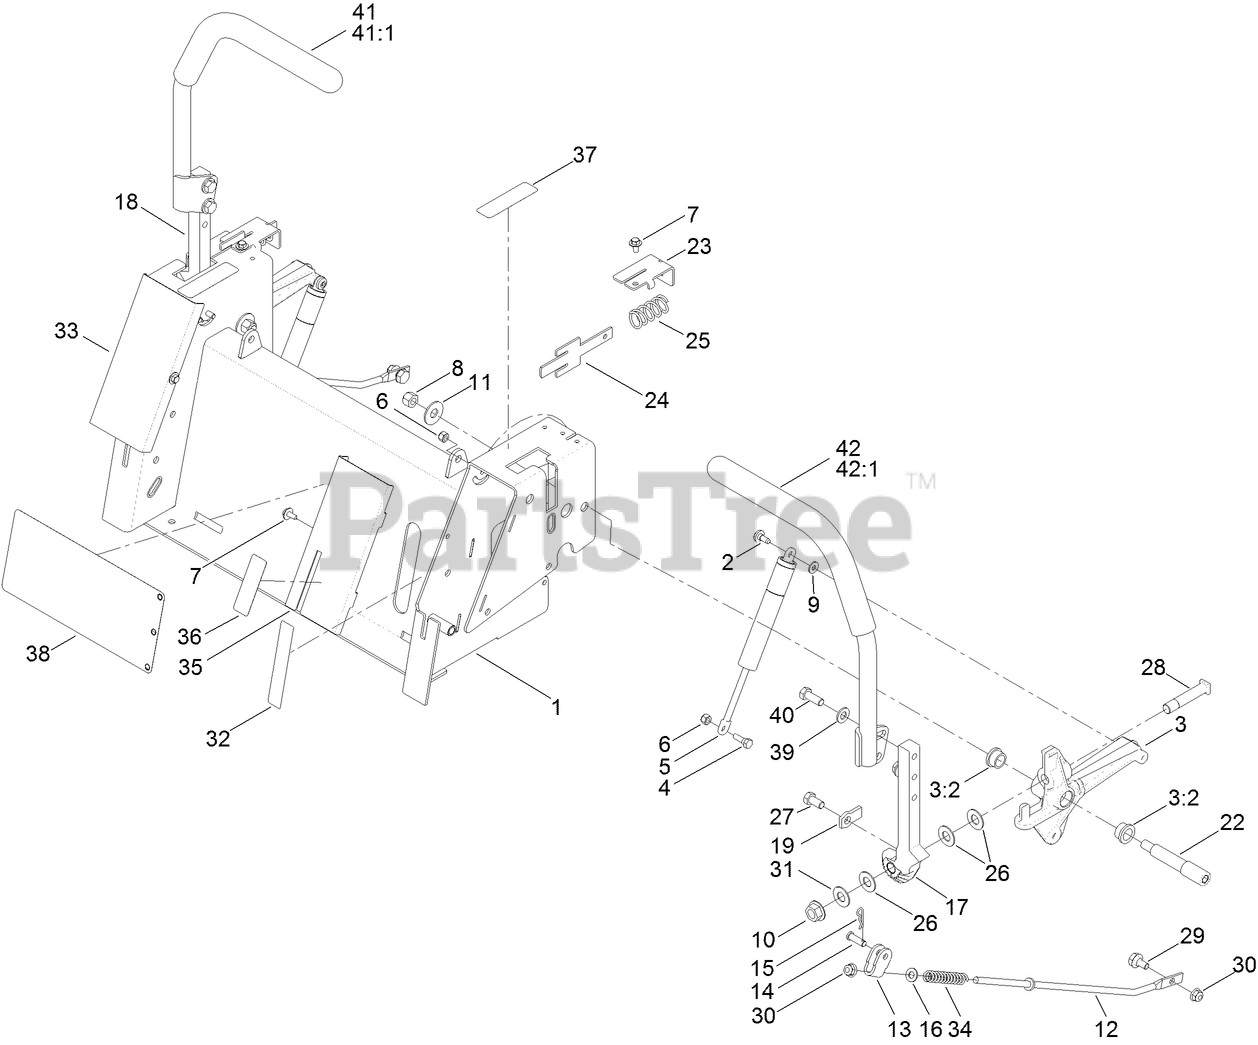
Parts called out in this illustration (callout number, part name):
1	BOX-CONTROL
2	SCREW-SHOULDER
3	ACTIVATOR ARM ASM
3:2	BUSHING
4	BOLT-SHOULDER
5	DAMPER
6	NUT-LOCK, NI
7	SCREW-HHFTF
8	NUT-LOCK, NI
9	WASHER
10	NUT-HF
11	WASHER-FLAT
12	ROD-CONTROL
13	BRACKET-CONTROL
14	PIN-CLEVIS
15	PIN-COTTER
16	WASHER-PLAIN
17	ARM-ACTUATOR, LH
18	ARM-ACTUATOR, RH
19	TAB-STOP
22	BOLT-SHOULDER
23	BRACKET-RETURN
24	PLATE-RETURN
25	SPRING-COMPRESSION
26	WASHER-PIVOT
27	SCREW-HH
28	BOLT-SHOULDER
29	BOLT-SHOULDER,HFH
30	NUT-HF, NI
31	WASHER-TEFLON
32	DECAL-FILL, FUEL
33	COVER-CONTROL, RH
34	SPRING-RETURN, NEUTRAL
35	COVER-CONTROL, LH
36	DECAL-BRAKE, PARKING
37	DECAL-CONTROL, MOTION
39	WASHER-FLAT
40	SCREW-HH
41	HANDLE-CONTROL, RH
42	HANDLE-CONTROL, LH
